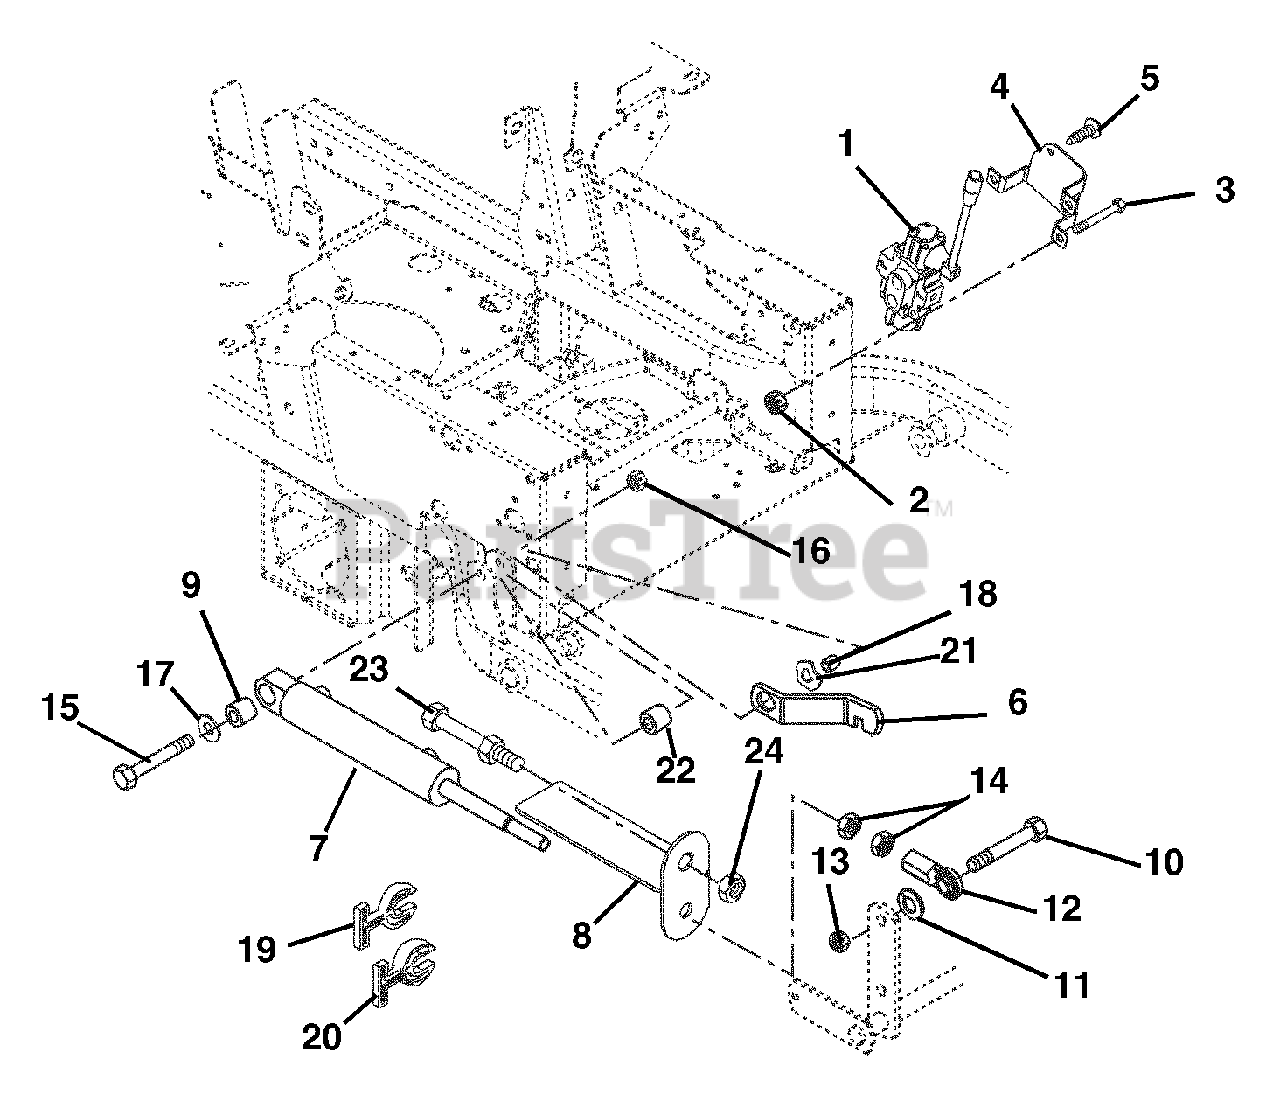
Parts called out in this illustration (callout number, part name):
1	VALVE, HYDRAULIC
2	@NUT-LK-TOP-FLG .31-18 YWZC
3	@BLT-HEX .31-18X2.50 GR5 YWZC
4	VALVE MOUNTING BRACKET -BLACK
5	@SCR-TAP .38-16X.50 HWH TR YWZ
7	CYLINDER - HYDRAULIC LIFT
8	STRAP, CUT INDICATOR/GUARD
9	BUSHING, .516X1.000X1.050 LG
10	BLT-HEX .62-11X2.25 YWZC GR8
11	@WSHR-LK .62X.156 REG YWZC
12	ROD END, 5/8 RH - FEMALE
13	@NUT-LK-CTR .62-11 YWZC
14	NUT-JAM .625-18 YWZC
15	@BLT-HEX .50-13X3.50 GR5 YWZC
16	@NUT-LK-TOP-FLG .50-13 YWZC
17	WSHR-FL-STL .515X1.625X.250 YZ
18	BSHG-FLG .515X.750X.285X1.120
19	STOP, CYLINDER .34 THK
20	STOP, CYLINDER .680 THK
21	WASHER-WAVE .760X1.120X.080
22	SPACER .516X1.000X.875
24	NUT-JAM CTRLK .75-16 YWZC
